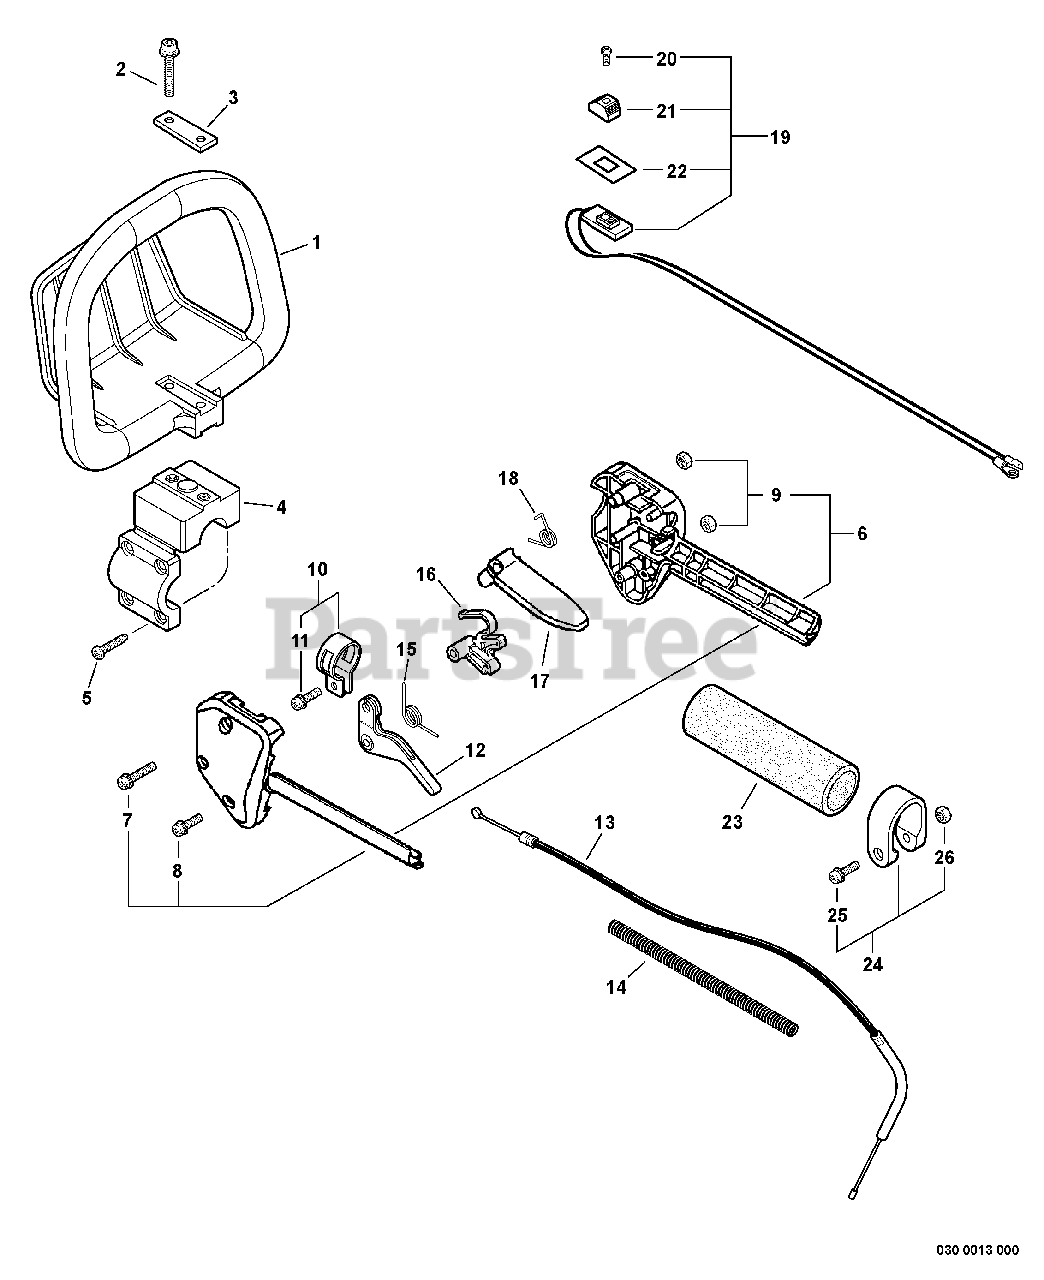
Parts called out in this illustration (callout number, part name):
1	HANDLE, SUPPORT
2	BOLT 5×30
3	PLATE, EYE
4	BRACKET, HANDLE
6	HANDLE KIT, CONTROL
7	SCREW 5×35
8	SCREW 5×25
9	NUT M5
10	CLAMP KIT
11	SCREW 5×14
12	TRIGGER, THROTTLE
13	CABLE, THROTTLE
14	TUBE, PROTECTIVE - CORRUGATED
15	SPRING, TORSION
16	LOCKOUT, THROTTLE
17	LEVER, THROTTLE LOCKOUT
18	SPRING, TORSION
19	SWITCH ASSY, ON-OFF
20	SCREW 3×10
21	KNOB, SWITCH - ORANGE
22	LABEL, SWITCH
23	GRIP, HANDLE
24	CLAMP KIT
25	SCREW 5×28
26	NUT M5
